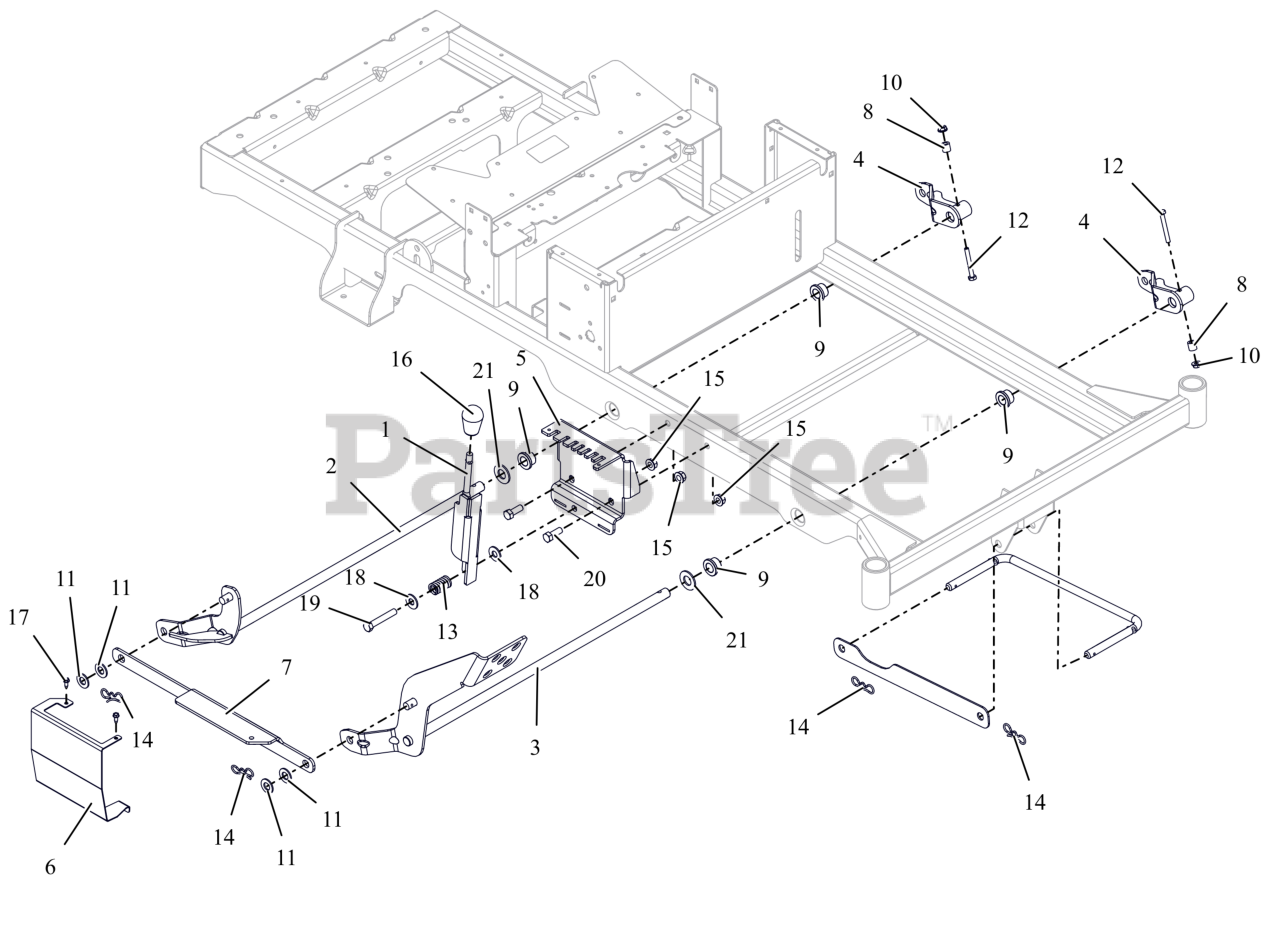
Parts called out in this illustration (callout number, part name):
1	WLDMT, HEIGHT OF CUT (ORANGE)
2	LINK- HOC EDGE DECK LIFT
3	WLDMT- PEDAL DECK LIFT EDGE
4	WLDMT, DECK LIFT ARM (ORANGE)
5	PLATE, HEIGHT (ORANGE)
6	GUARD, DECK HOC (ORANGE)
7	LINK, LIFT /HOC (ORANGE)
8	BSHG-SLV .265X.500X.500
9	BSHG-FLG .629X.879X.469X1.250
10	NUT-LK-CTR-FLG .25-20 ZC120
11	WSHR-FL-NYL .518X1.000X.080
12	BLT, HEX .25-20X2.00 G5 ZCC
13	SPRG, COMPRESSION
14	PIN, BOWTIE .091X1.875 ZCC
15	NUT-LK-CTR-FLG .375-16 GF ZCC
16	KNOB,SOFT TEARDROP,PUSH-ON BLK
17	SCR,TAP #10-24X.50 HWH TR ZCC
18	WSHR,FLT .438X1.00X.083 ZCC
19	BLT,HEX .38-16X2.25 G5 ZCC
20	BLT,HEX .38-16X1.00 G5 ZCC
21	WSHR, FLT .656X1.313X.095 ZCC
